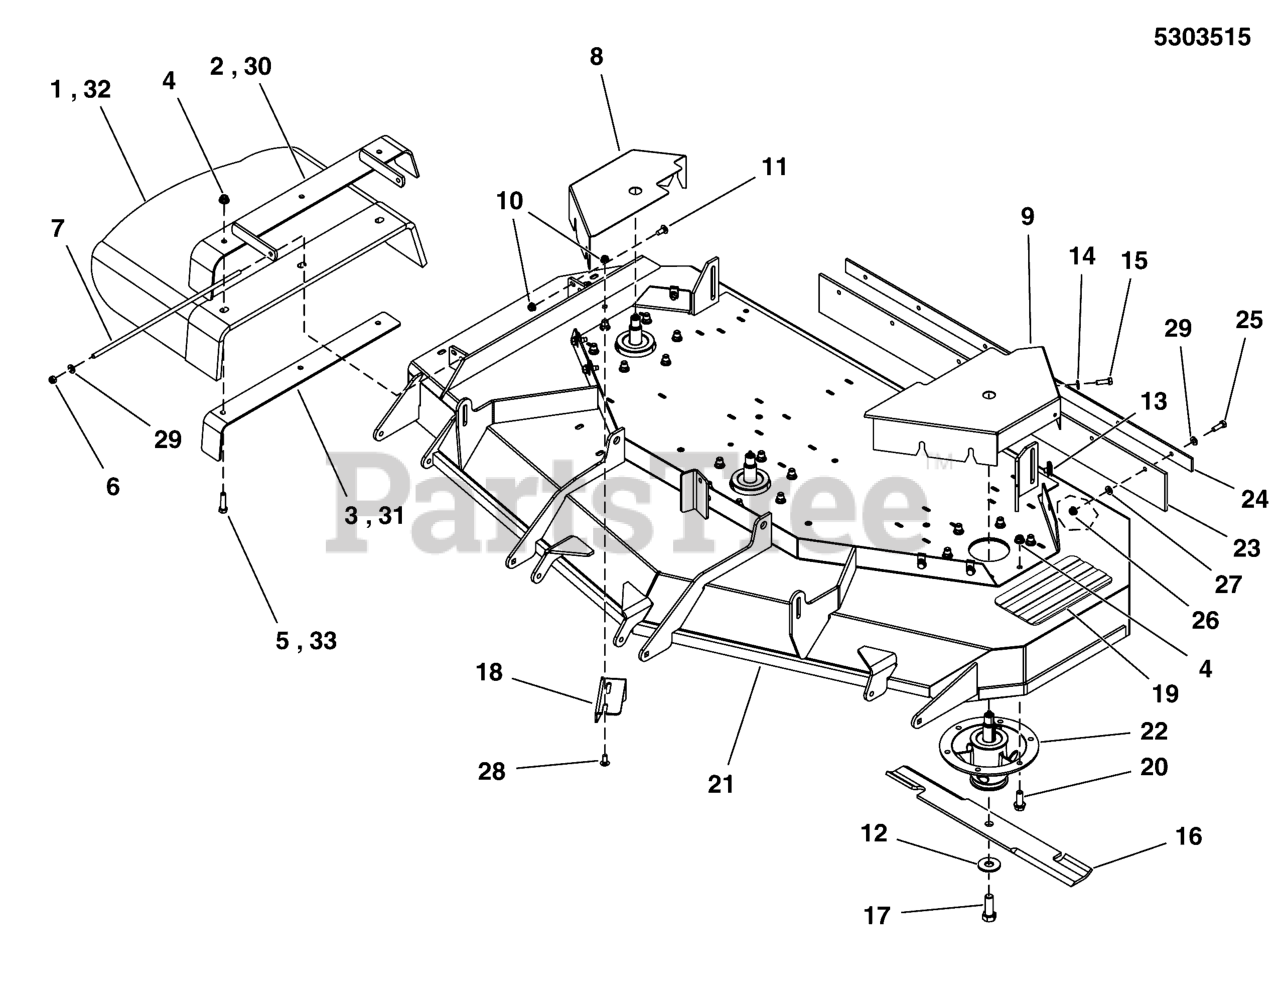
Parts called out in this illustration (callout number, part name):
1	CHUTE, DISCHARGE, BEND RUBBER (SV)
2	WELD, FRAME CHUTE, 61 - BLK
3	SUPPORT, DISCHARGE CHUTE, 61/72 - BLK
4	NUT, 3/8-16 HEX NYLOCK FLANGE
5	BOLT, 3/8-16 X 1-1/2" GD5 CZ
6	NUT, 5/16-24 HEX NYLON LOCK
7	ROD, MOUNT, CHUTE 61, CZ
8	GUARD, 61", RH - RED
9	GUARD, 61 - LH - RED
10	NUT, 5/16-18 HEX NYLOCK FLANGE
11	BOLT, 5/16-18 X 3/4 GD5
12	WASHER, BLADE BOLT, 9/16" F436, CZ
13	BODY CLIP, 5/16-18-7GA MATERIAL
14	WASHER, 5/16 F436 FLAT
15	BOLT, 5/16-18 X 3/4 GD5
16	BLADE SET, 61 DECK (3)
17	BOLT, 5/8-11 X 1-3/4 GD8
18	PLATE, DEFLECTOR - BLK
19	SAFETY WALK, 9.75 X 6.00
20	BOLT, 3/8-16 X 1, FLANGE, GD 5, CZ
21	DECK SHELL W/ DECALS, 61, IS2100Z (SV)
21	DECK SHELL W/ DECALS, 61, IS2100Z EXP (SV)
22	SPINDLE ASSM, CAST IRON 8.0-6 BOLT
23	FLAP, STRIPER, 61 DECK
24	PLATE, SUPPORT - BLK
25	BOLT, 5/16-18 X 1 GD5 YZ
26	NUT, 5/16-18 HEX NYLOCK FLANGE
27	5/16 PUSH-ON NUT RETAINER, STL, CZ
28	BOLT, 5/16-18 X 3/4, CARRIAGE
29	WASHER, 5/16" SAE
30	MOUNT
31	SUPPORT, DISCHARGE CHUTE - BLK
32	CHUTE, RUBBER DISCHARGE (5104442)
33	BOLT, 3/8-16 X 1-1/2, CARRIAGE, GD5, CZ
